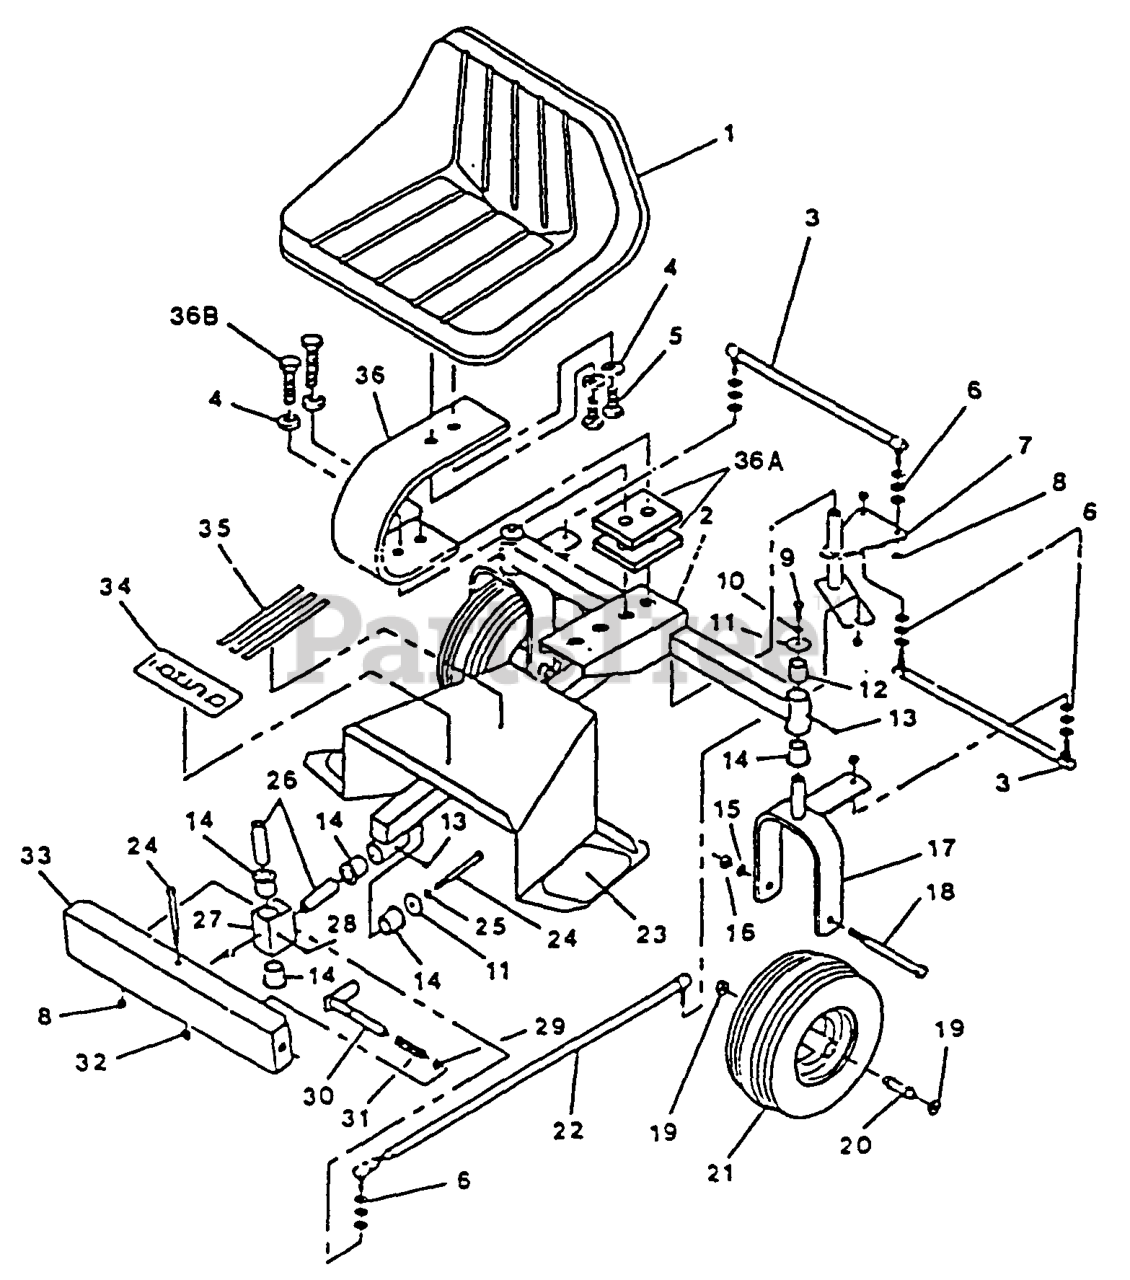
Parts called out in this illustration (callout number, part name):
3	ROD,STABILIZING
7	WLD,CRANK
12	BEARING,STRAIGHT
17	WLD,WHEEL SUPPORT
20	WLD,WHEEL SPACER
22	ROD-STEERING
23	PAD,ANTI SKID
26	PIN,CONNECTING
27	ASM,MOUNTING SWIVEL
31	SPRING,HITCH RELEASE
33	WLD,HITCH
36	SPRING,SULKY SEAT
